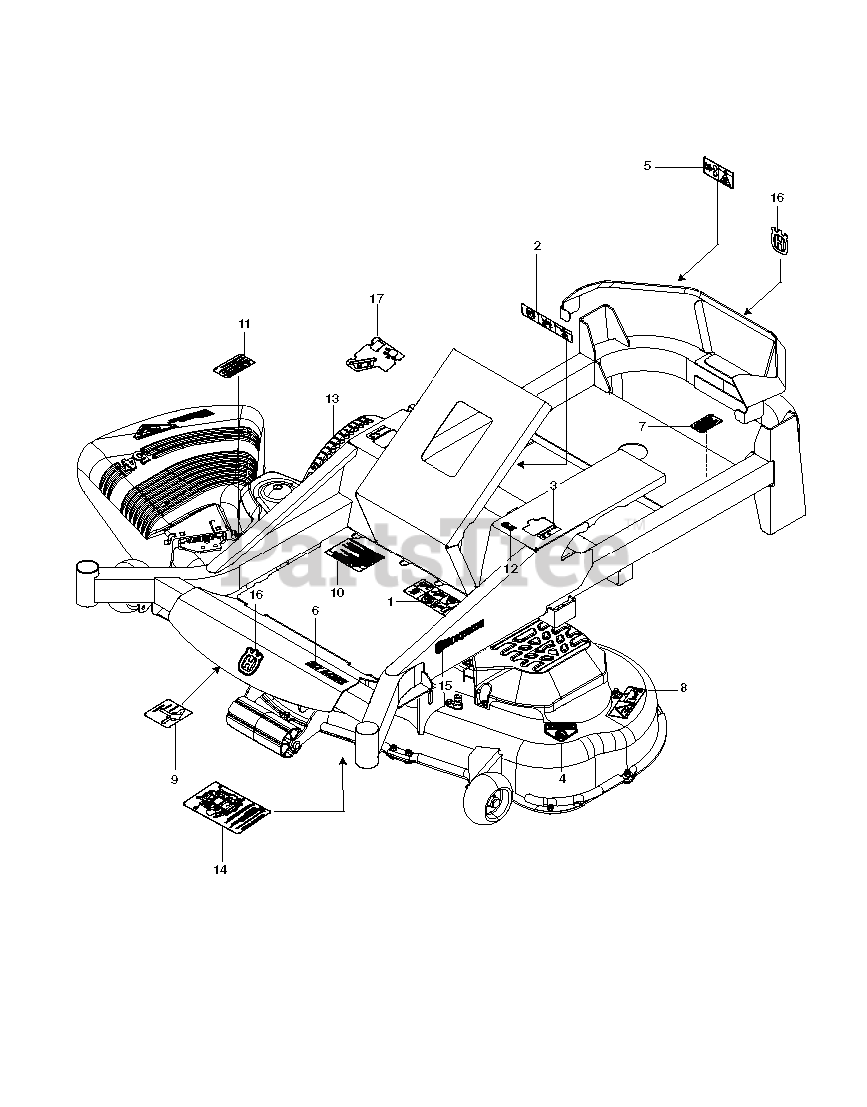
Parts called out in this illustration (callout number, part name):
1	DECAL, WARNING
2	EURO DECAL-BATTERY WARNIN6
3	DECAL, MOTION CONTROL
4	DECAL, CPSC
5	DECAL, BELT DRIVE
6	DECAL, MZ5424S
7	DECAL, PROP. 65
8	DECAL, EURO SEVERING
9	DECAL, BELT ROUTING
10	DECAL, WARNING
11	DECAL, CAUTION
12	DECAL, F.S.T.
13	DECAL, HEIGHT ADJUST
14	DECAL, SERVICE
15	RP.DECAL.BADGE.170MM.TEXTLOGO
16	DECAL.AUGER.HUSQ.CROWN.SNOW
17	DECAL, CONSOLE HUS
